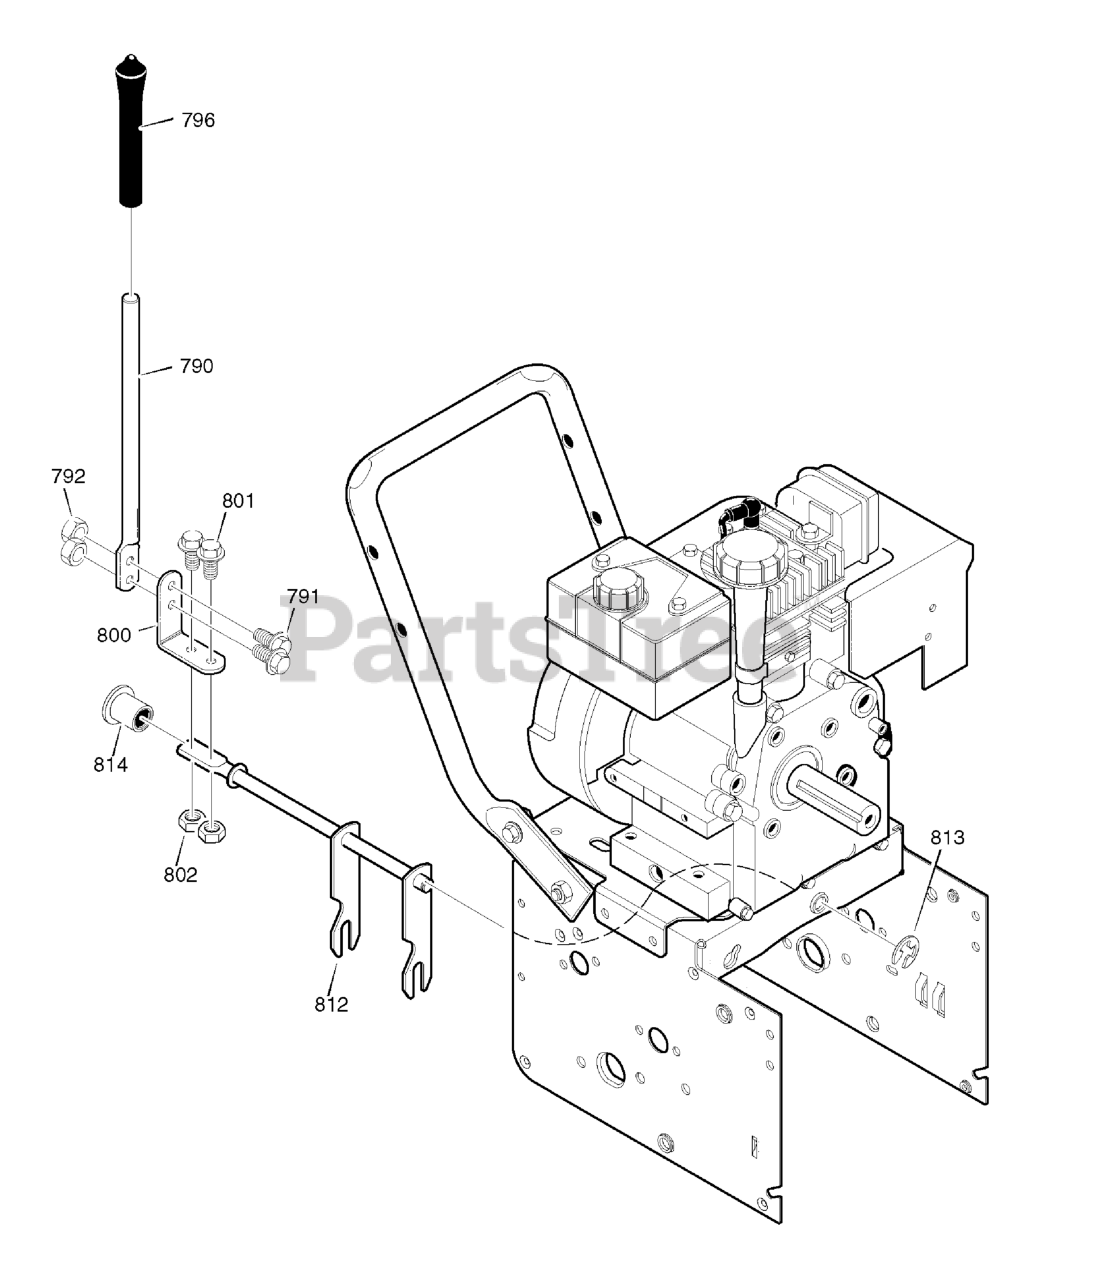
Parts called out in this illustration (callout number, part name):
790	ROD, SHIFT
791	SCREW, 1/4-20X.75
792	NUT, 1/4-20
796	KNOB, SLIP
800	LEVER, SPRING
801	SCREW, 1/4-20X.75
802	NUT, 1/4-20
812	ROD ASSY., SPEED SELECT
813	RETAINER, RING
814	BEARING, FLANGED
